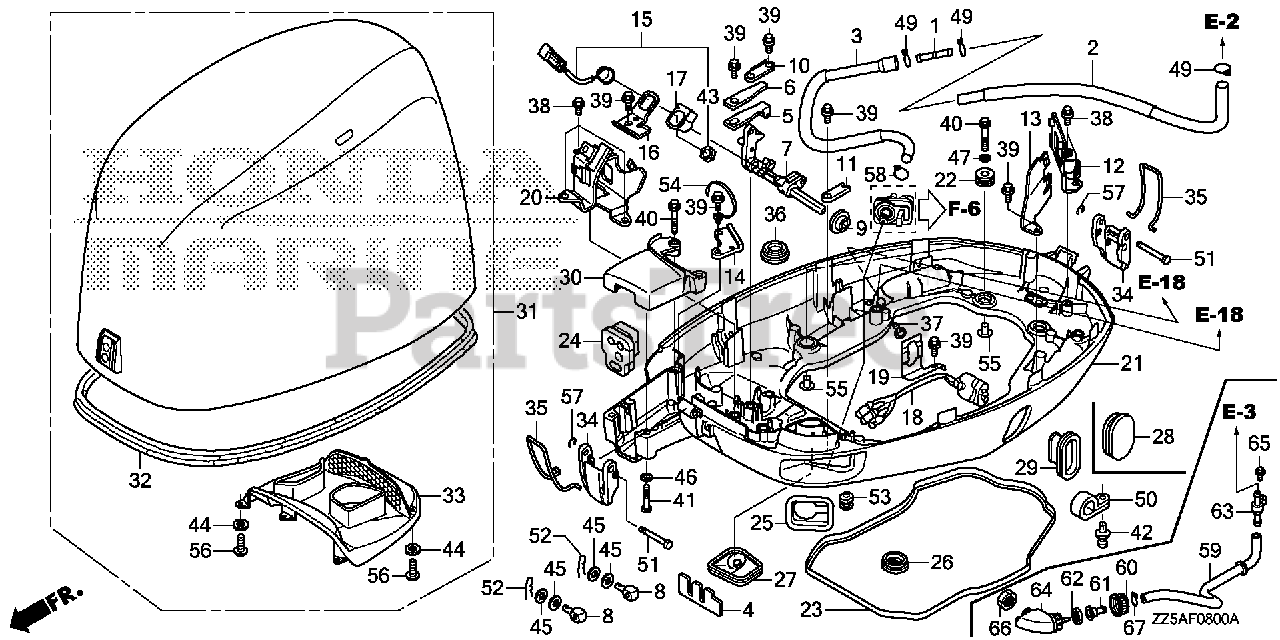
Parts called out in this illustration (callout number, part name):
1	JOINT, FUEL FEED HOSE
2	TUBE A, FUEL (FKM)
3	TUBE D, FUEL (FKM)
4	PLATE, REMOTE CONTROL CABLE
5	SPRING, CLICK
6	SPRING, CLICK ASSIST
7	SHAFT, SHIFT
8	PIVOT, SHIFT
9	BUSH, SHAFT
10	PLATE, SHIFT
11	PLATE, SHIFT SHAFT
12	BRACKET, REGULATOR
13	BRACKET B, CONNECTOR
14	BRACKET, CABLE CLIP
15	SWITCH ASSY., NEUTRAL
16	BRACKET, NEUTRAL SWITCH
17	PLATE, NEUTRAL SWITCH
18	SWITCH ASSY., POWER TILT
19	STAY, POWER TILT SWITCH
20	BRACKET, MAIN RELAY
21	CASE, ENGINE (LOWER) *NHB14M* (AQUA MARINE SILVER METALLIC)
22	GROMMET, CASE (LOWER)
23	SEAL, CASE (LOWER)
24	GROMMET, CASE (LOWER) (A)
25	GROMMET, CASE (LOWER) (B)
26	GROMMET, CASE (LOWER) (C)
27	GROMMET, CASE (LOWER) (E)
29	GROMMET, CASE (LOWER)
30	CASE, SEPARATE *NHB14M* (AQUA MARINE SILVER METALLIC)
31	COVER, ENGINE *NHB14M* (AQUA MARINE SILVER METALLIC)
32	SEAL, ENGINE COVER
33	GUIDE, ENGINE COVER AIR
34	LEVER, FASTENER
35	WIRE, FASTENER
36	CAP, L. SIDE COVER
37	GROMMET, WATER CHECK
38	BOLT, FLANGE (6X14) (CT200)
39	BOLT, FLANGE (6X12) (CT200)
40	BOLT, FLANGE (6X28)
41	BOLT, HEX. (6X40)
42	SCREW, RIVET (5X10)
43	NUT, HEX. (20MM)
44	WASHER, PLAIN (5MM)
45	WASHER, PLAIN (6MM)
46	WASHER, PLAIN (6MM)
47	WASHER, PLAIN (6MM)
49	CLIP, TUBE (B12)
50	CLIP (14MM)
51	PIN (5X44.5)
52	PIN, LOCK SPECIAL (6MM)
54	CLIP, HARNESS BAND (155.3MM) (BLACK)
55	COLLAR, MODULE IGNITION CONTROL CASE (CDI)
56	SCREW, PAN (5X12)
57	E-RING (4MM)
58	CLIP, TUBE
